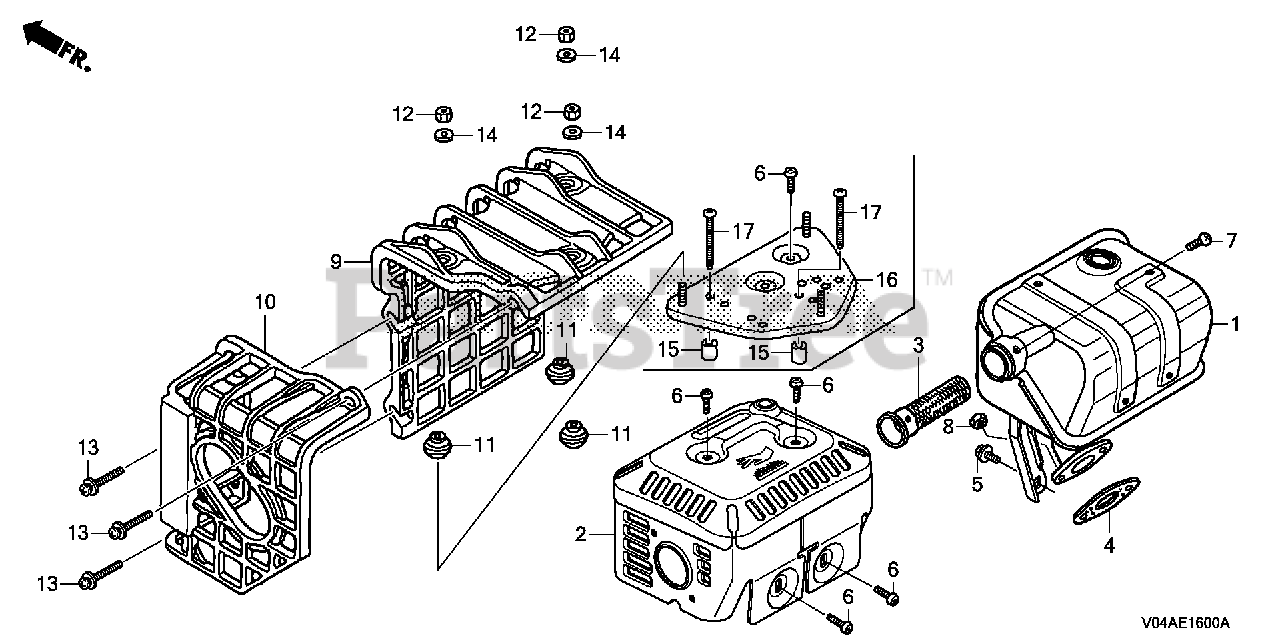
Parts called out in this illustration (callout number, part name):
1	MUFFLER (ARRESTER)
2	PROTECTOR, MUFFLER
3	ARRESTER, SPARK
4	GASKET, MUFFLER
5	BOLT, FLANGE (6X13)
6	SCREW, TAPPING (5X8)
7	SCREW, TAPPING (4X6)
8	NUT, HEX. (8MM)
9	COVER, MUFFLER PROTECTOR
10	COVER, RR. MUFFLER
11	SPACER, MUFFLER COVER
12	NUT, HEX. (5MM)
13	SCREW-WASHER (6X20)
14	WASHER, PLAIN (5MM)
15	COLLAR, AIR CLEANER HOUSING
16	BASE, MUFFLER COVER
17	SCREW, TAPPING (5X25)
